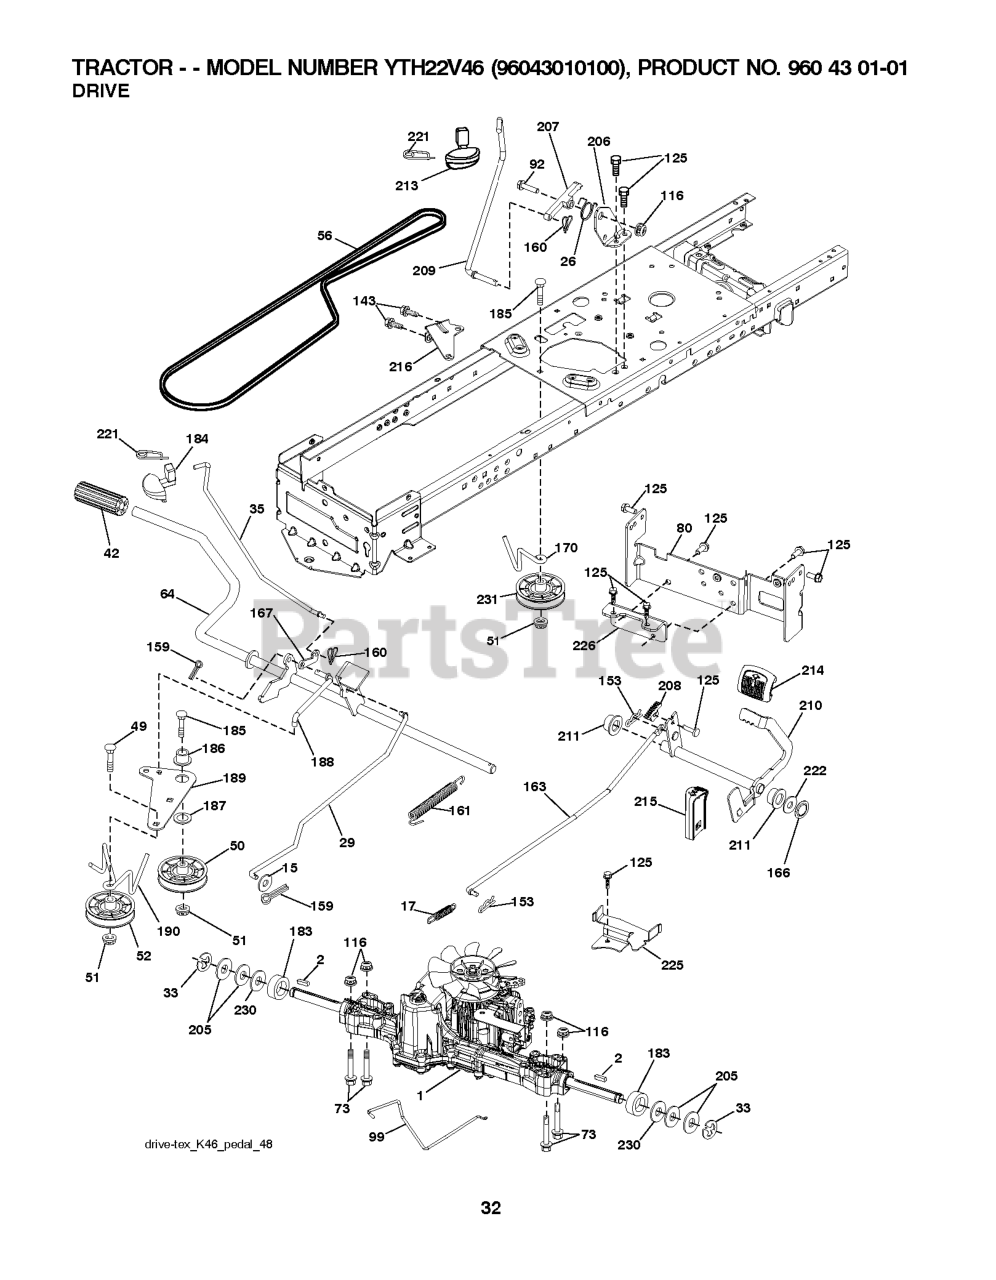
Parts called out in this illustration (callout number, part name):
1	TRANSAXLE(K46BT).PDL.
2	SQUARE KEY
15	WASHER
17	SPRING.BRAKE.K46.GREEN
26	SPRING.RETURN.CRUISE
29	ROD.BRAKE.K46
35	ROD.BRAKE.PARKING.GT.H
42	PEDAL COVER T
50	IDLER.FLAT.910.OFFSET
51	NUT LOCK FLG 3/8-16 UNC
52	IDLER.V-GROOVE.910.OFFSET
56	V-BELT.MOWER.92.40.42/K46
64	SHAFT.ASM.PEDAL.BRK.CNTR
73	BOLT HEX 5/16-18 GR 5
80	STRAP TORQUE
92	BOLT
99	ROD.SPRING.BYPASS.K46.LT.Z
116	NUT LOCK HEX FLANGE 5/16-18
125	SCREW
143	Screw 5/16-18 x 1/2 Hex, Self Tapping 5/16-18 x 1/2
153	RETAINER M
159	COTTER PIN
160	RETAINER CLIP
161	SPRING, RETURN LT
163	ROD.CONTROL.PEDAL.K46
166	NUT.PUSH.625
167	LATCH.BRAKE.SPRING
170	KEEPER.CENTER SPAN.1.688
183	SPACER AXLE
184	HANDLE.PARKG.BRK.HUSQ X667
186	SPACER.RETAINER
187	WASHER 12/32X2X10GA
188	RP.LINK.CLUTCH.GROUND.DRIVE
189	BELLCRANK.GROUND.DRIVE.TEX.
190	KEEPER.BELLCRANK.DRIVE
206	BRKT.MOUNT.LATCH.CRUIS
207	LATCH.CONTROL.CRUISE
208	GEAR.SECTOR.CONTROL.CR
209	ROD.CONTROL.CRUISE.GT.
210	ROCKER.ASM.PEDAL.CONTR
211	BEARING.NYLON
213	KNOB.CONTROL.CRUSIE.HU
214	PEDAL.FORWARD.PAD.TEX
215	PEDAL.REVERSE.TEX.GT.4
216	BRACKET.PULLEY.IDLER.W/TEX
221	RETAINER.SPRING.CLIP.H
222	WASHER 21/32 X 1-1/4 X 10 GA.
225	KEEPER.BELT.TRANSAXLE.K46
226	BRACKET.MOUNT.TORQUE.K46.TLT
230	WASHER.HARDENED
231	IDLER.V-GROOVE.1.688.OFFSET
